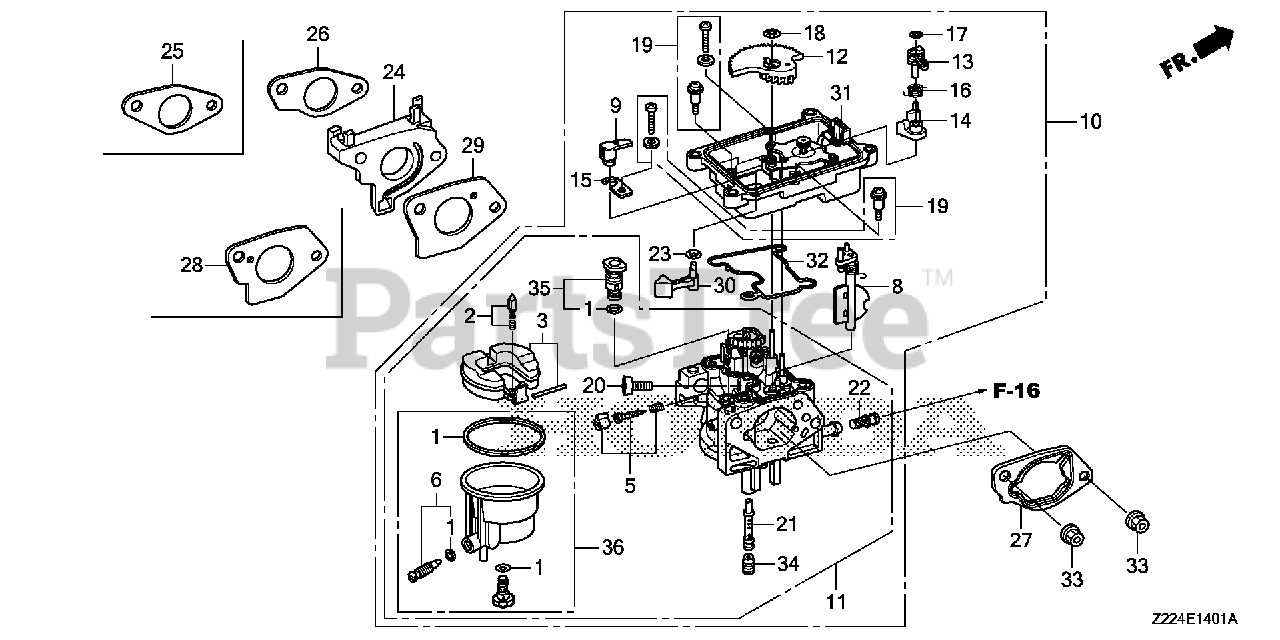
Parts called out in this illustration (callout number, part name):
1	GASKET SET
2	VALVE SET, FLOAT
4	CHAMBER SET, FLOAT
5	SCREW SET, PILOT
6	SCREW SET, DRAIN
7	BOLT KIT, FUEL CHAMBER
7	SCREW SET
9	ARM, MANUAL START
10	CARBURETOR ASSY. (BE96A A)
11	CARBURETOR SET
12	GEAR, MIDDLE
13	ARM, CHOKE
14	LEVER, CHOKE CONTROL
16	SPRING, TORSION COIL
17	CLIP, SPECIAL
18	CLIP, SPECIAL
20	SCREW, STOP
21	NOZZLE, MAIN
22	SCREEN, FUEL STRAINER
23	O-RING (4.8X1.9)
24	INSULATOR, CARBURETOR
26	GASKET, CARBURETOR INSULATOR
27	SPACER, CARBURETOR
29	GASKET, CARBURETOR
30	LEVER, MANUAL START
31	CASE, MOTOR
33	NUT, FLANGE (6MM)
34	JET, MAIN (#98)
34	JET, MAIN (#102)
34	JET, MAIN (#105)
35	JET SET, PILOT (#45)
36	BOLT KIT, FUEL CHAMBER
